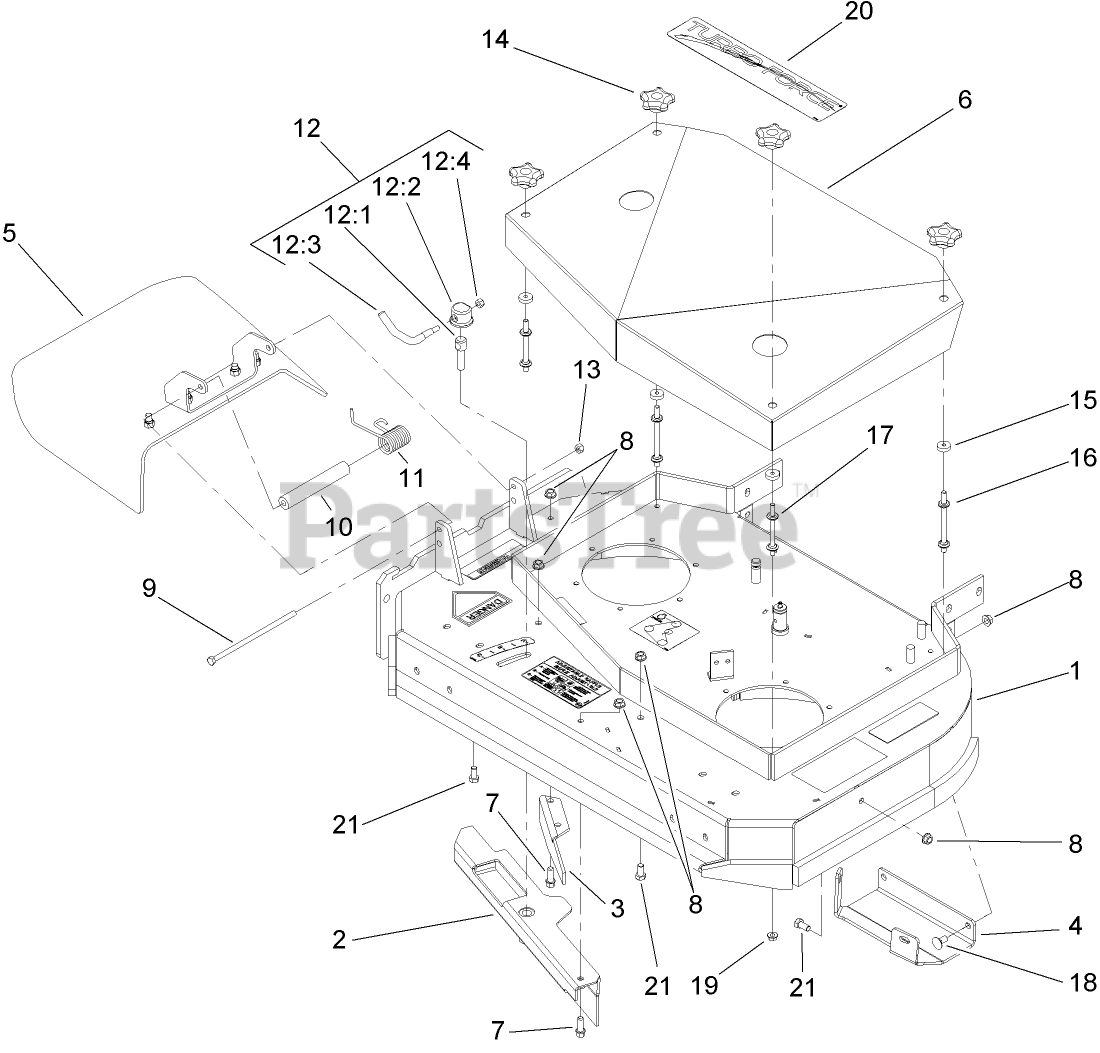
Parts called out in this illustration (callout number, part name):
1	DECK ASM
2	ADJUSTABLE BAFFLE
3	BAFFLE-DISCHARGE
4	PLATE-SKID
5	DEFLECTOR ASM
6	COVER-DECK
7	SCREW-HWH
8	NUT-HHF, WHIZ
9	SCREW-HH
10	SPACER
11	SPRING-TORSION
12	LEVER ASM
12:1	Screw-Lock
12:2	CAP-LOCK
12:3	Lever-Lock
12:4	NUT-LOCK, NI
13	NUT-LOCK, NI
14	KNOB-HANDLE
15	WASHER
16	STUD-SHIELD, BELT (LONG)
17	STUD-SHIELD, BELT (SHORT)
18	SCREW-CARR
19	NUT-HF
20	DECAL
21	SCREW-HH
